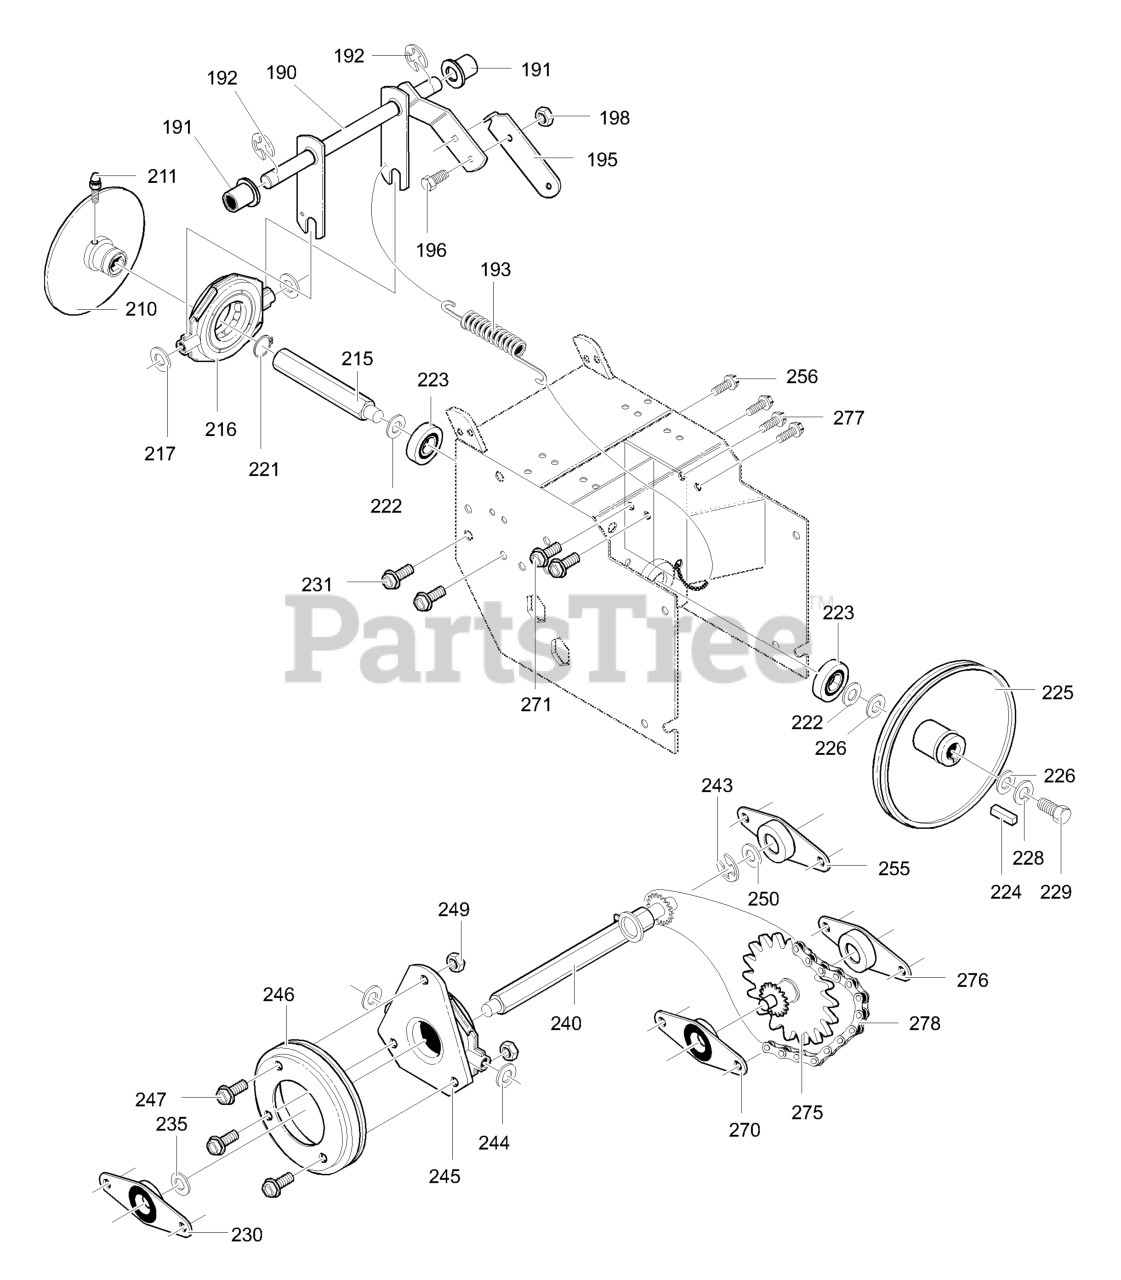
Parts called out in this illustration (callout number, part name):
190	LEVER, ASSY TRACTION CLUTCH
191	BEARING, FLANGE
192	RING, RET E
193	SPRING, RETURN
195	LEVER, SPRING
196	SCREW, 1/4-20X .63
198	NUT, 1/4-20 REGHEXCTRLK
210	DISC, ASSY
211	ZERK, GREASE
215	SHAFT, HEX TRACTION
216	BEARING, TRUNION
217	FLATWASHER, .53 X1.00X.063
221	RING, RETEX
222	FLATWASHER, .680X1.12X.060
223	BEARING, BALL
224	KEY, SQUARE
225	PULLEY, V3L 6.50X .56
226	WASHER, WAVE
227	FLATWASHER, .281X1.00X.063
228	WASHER, SPLIT .26X.50X.06
229	SCREW, 1/4-20X .75 HHC
230	BEARING & RETAINER
231	SCREW, 5/16-18 x 0.50
235	WASHER,.502X .75X.0605
240	HEX, ASSY#40-8T W/PBRG
243	RING, RETEX
244	FLATWASHER, .53 X1.00X.063
245	BEARING, TRUNION
246	WHEEL, ASSY FRICTION
247	SCREW, 1/4-20X .63
249	NUT, 1/4-20 HEXKEPS
250	WASHER,.502X .75X.0605
255	BEARING & RETAINER
256	SCREW, 5/16-18 x 0.50
270	BEARING & RETAINER
271	SCREW, 5/16-18 x 0.50
275	JACK, ASSY#41-36/7
276	BEARING & RETAINER
277	SCREW
278	CHAIN ROLLER
